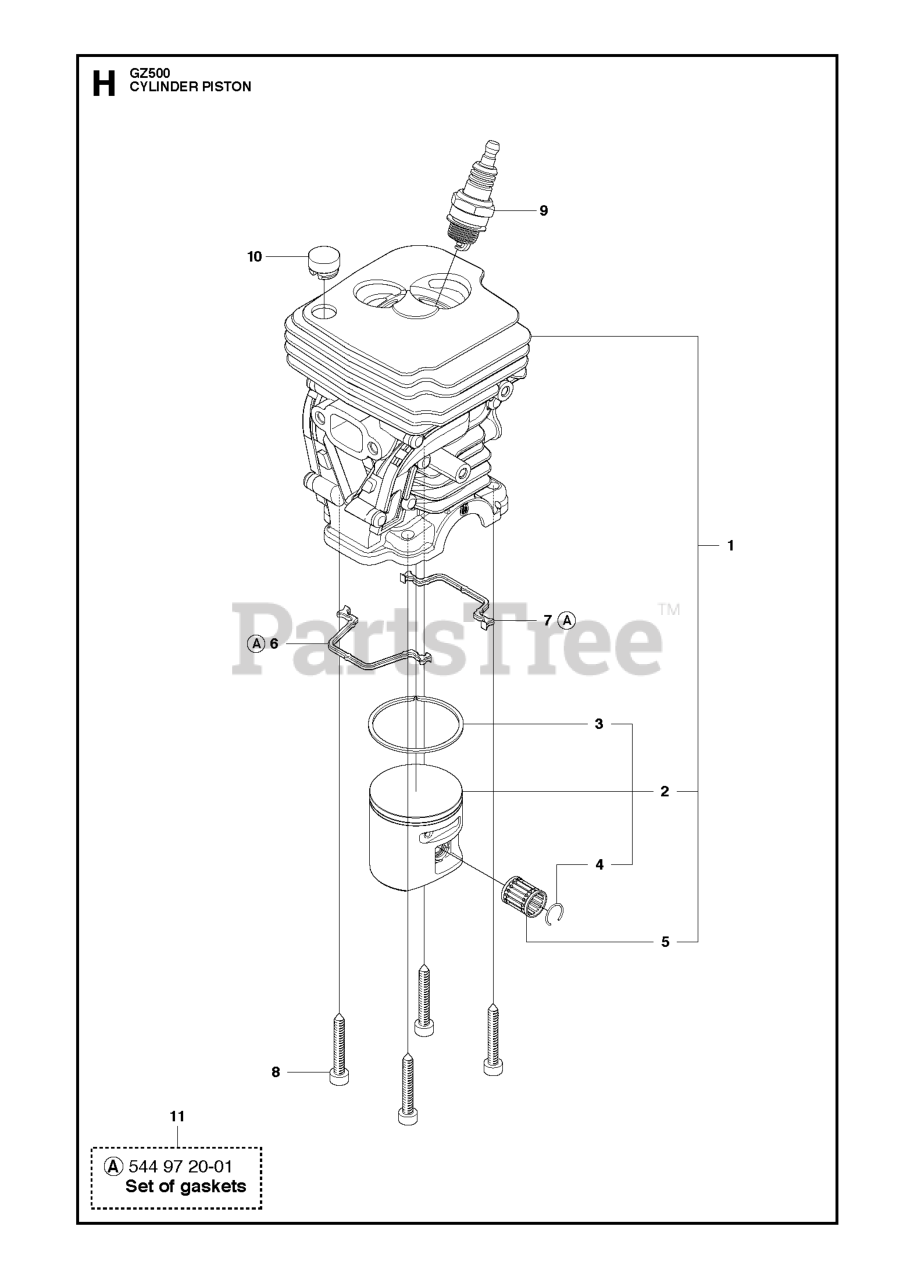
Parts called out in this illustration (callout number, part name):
1	CYLINDER
2	PISTON ASSY
3	PISTON RING
5	NEEDLE BEARING
9	HQT-1 HH SPARK PLUG - BPMR7A
11	GASKET KIT
